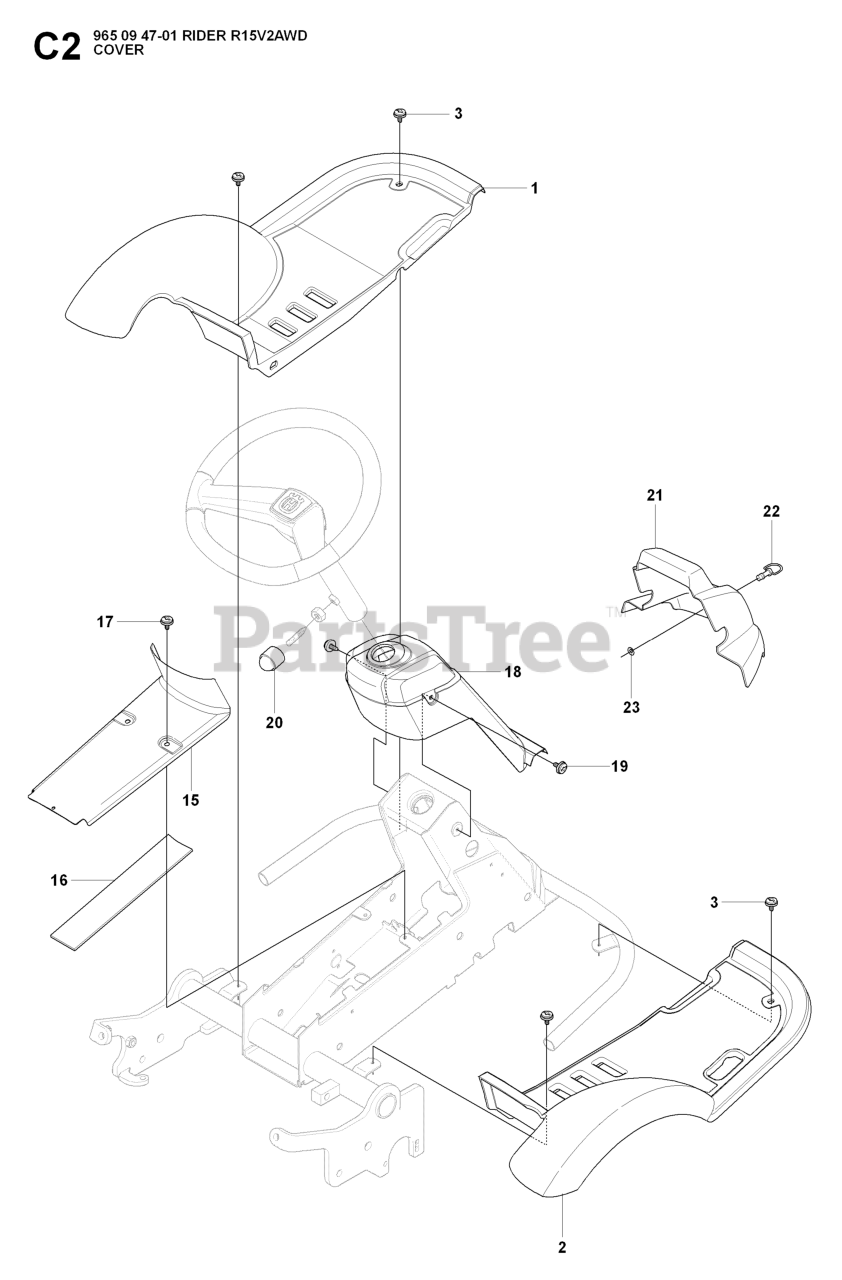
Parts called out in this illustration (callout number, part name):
1	FOOT PLATE
2	FOOT PLATE
20	PROTECTIVE COVER
22	BOLT
